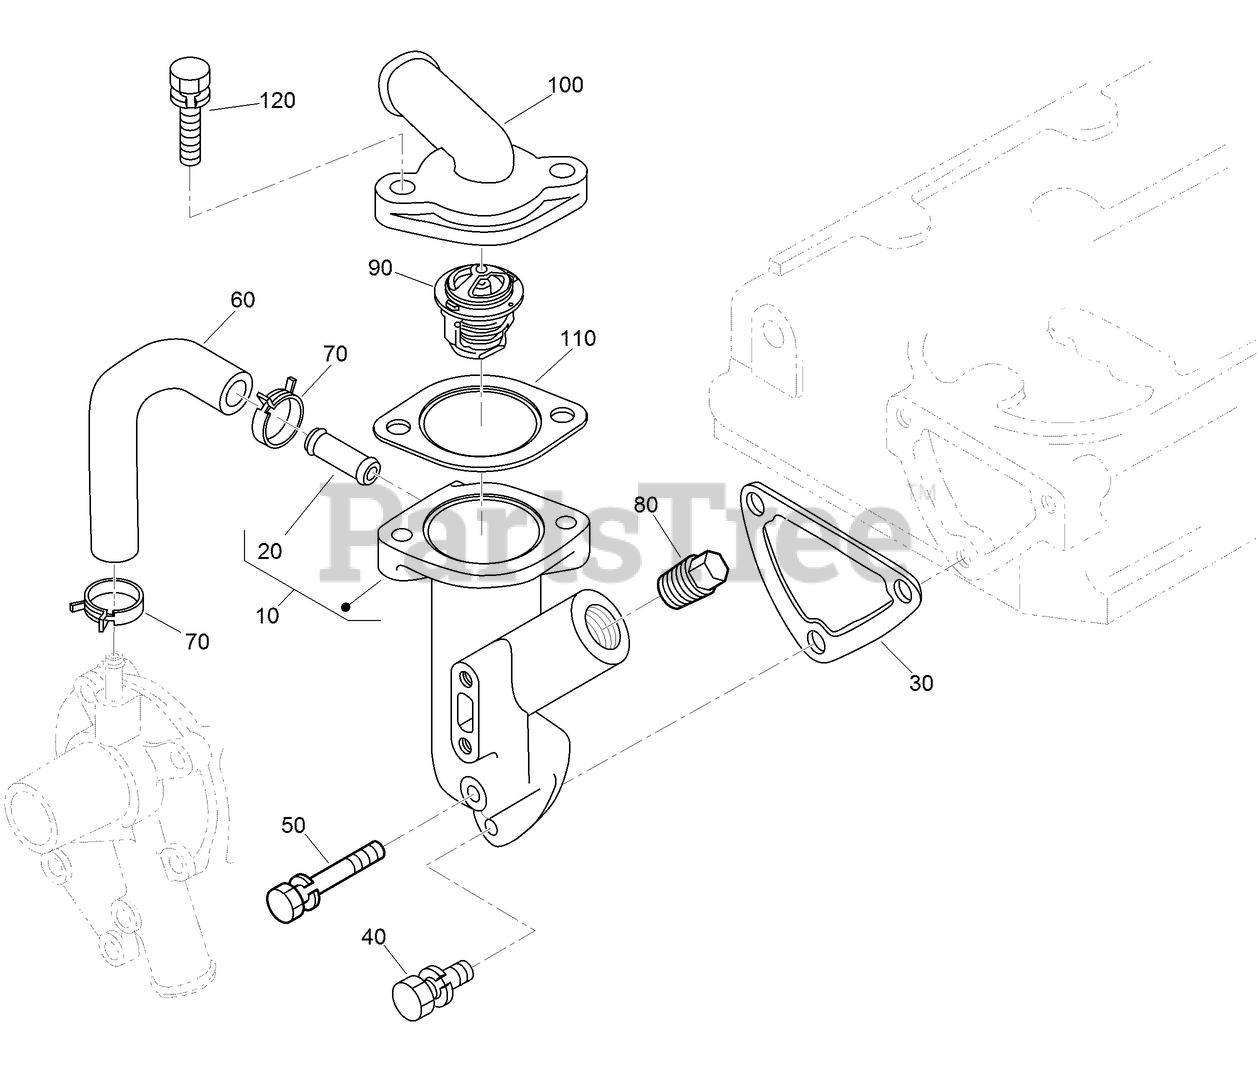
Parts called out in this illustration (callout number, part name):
10	WATER FLANGE ASM
20	PIPE-RETURN, WATER
30	GASKET-FLANGE, WATER
50	BOLT-SEMS
60	PIPE-RETURN, WATER
70	CLAMP-HOSE
90	THERMOSTAT ASM
100	COVER-THERMOSTAT
110	GASKET-THERMOSTAT
